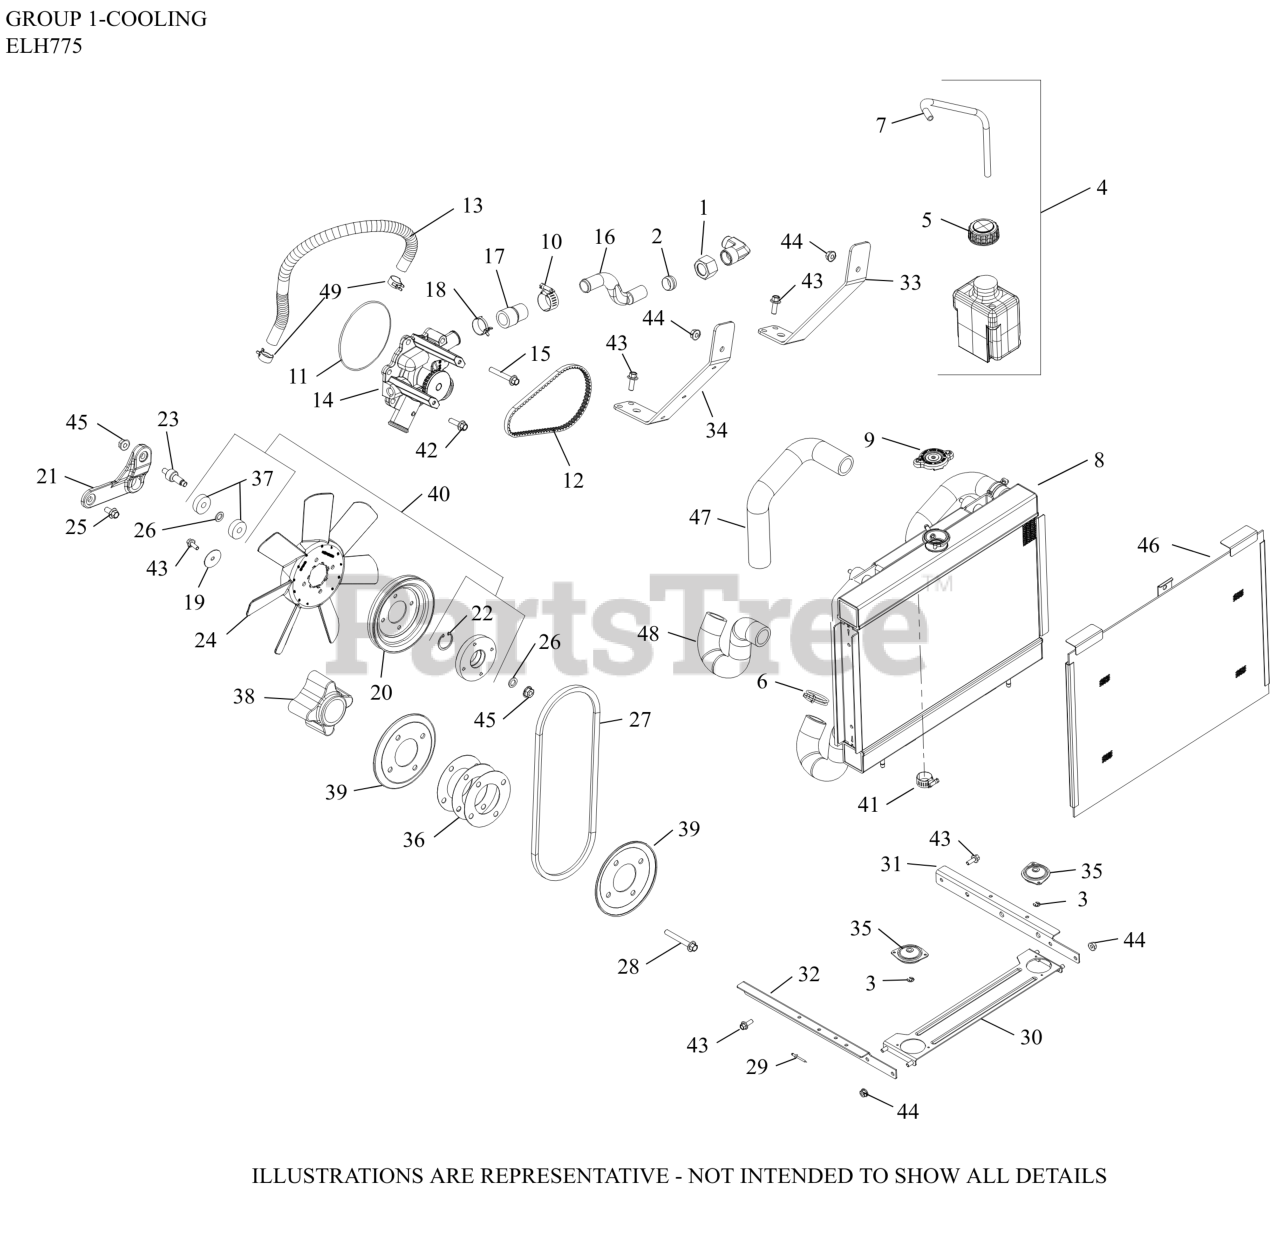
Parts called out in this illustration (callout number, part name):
3	RETAINER, E-CLIP
4	KIT, OVERFLOW BOTTLE
5	CAP, OVERFLOW
6	CLAMP, THERMOSTAT HSG OUTLET
7	HOSE, OVERFLOW
8	RADIATOR ASSEMBLY
9	CAP, RADIATOR
10	CLAMP, HOSE
12	BELT, WATER PUMP
13	HOSE, BY-PASS (12.00")
14	KIT, WATER PUMP
15	SCREW, FLG M6X1.0X40
16	TUBE, CROSSOVER (METAL)
17	TUBE, CROSSOVER (RUBBER)
19	WASHER, SPRING 1/4"
20	PULLEY, FAN
21	BRACKET, FAN
22	RING, RETAINER-INTL O.D. 30MM
23	KIT, FAN SHAFT
24	FAN, AXIAL PULLER
25	SCREW, FLG 8X1.25X16
27	BELT, FAN
28	SCREW, FLG M8X1.25X60
30	BRACKET, RADIATOR CROSS
31	BRCKT KIT, LWR RADIATOR #1
32	BRCKT KIT, LWR RADIATOR #2
33	BRACKET,UPPER RADIATOR #1 SIDE
34	BRACKET, UPPER RADIATOR #2 SIDE
35	MOUNT, PLATEFORM
36	SHIM, CRANKSHAFT PULLEY
37	BEARING, BALL
38	ADAPTER, CRANKSHAFT PULLEY
39	PULLEY, CRANKSHAFT
40	KIT, BEARING CARRIER
41	CLAMP, HOSE
42	SCREW, FLG M6x1.0x20
43	SCREW, FLG M6X1.0X16
44	NUT, FLG M6X1.0
45	NUT, FLG M8X1.25
46	SCREEN, GRASS (FLAT)-USE 66 162 12-S
47	HOSE, THERMOSTAT TO RADIATOR
48	HOSE, RADIATOR TO WATER PUMP
